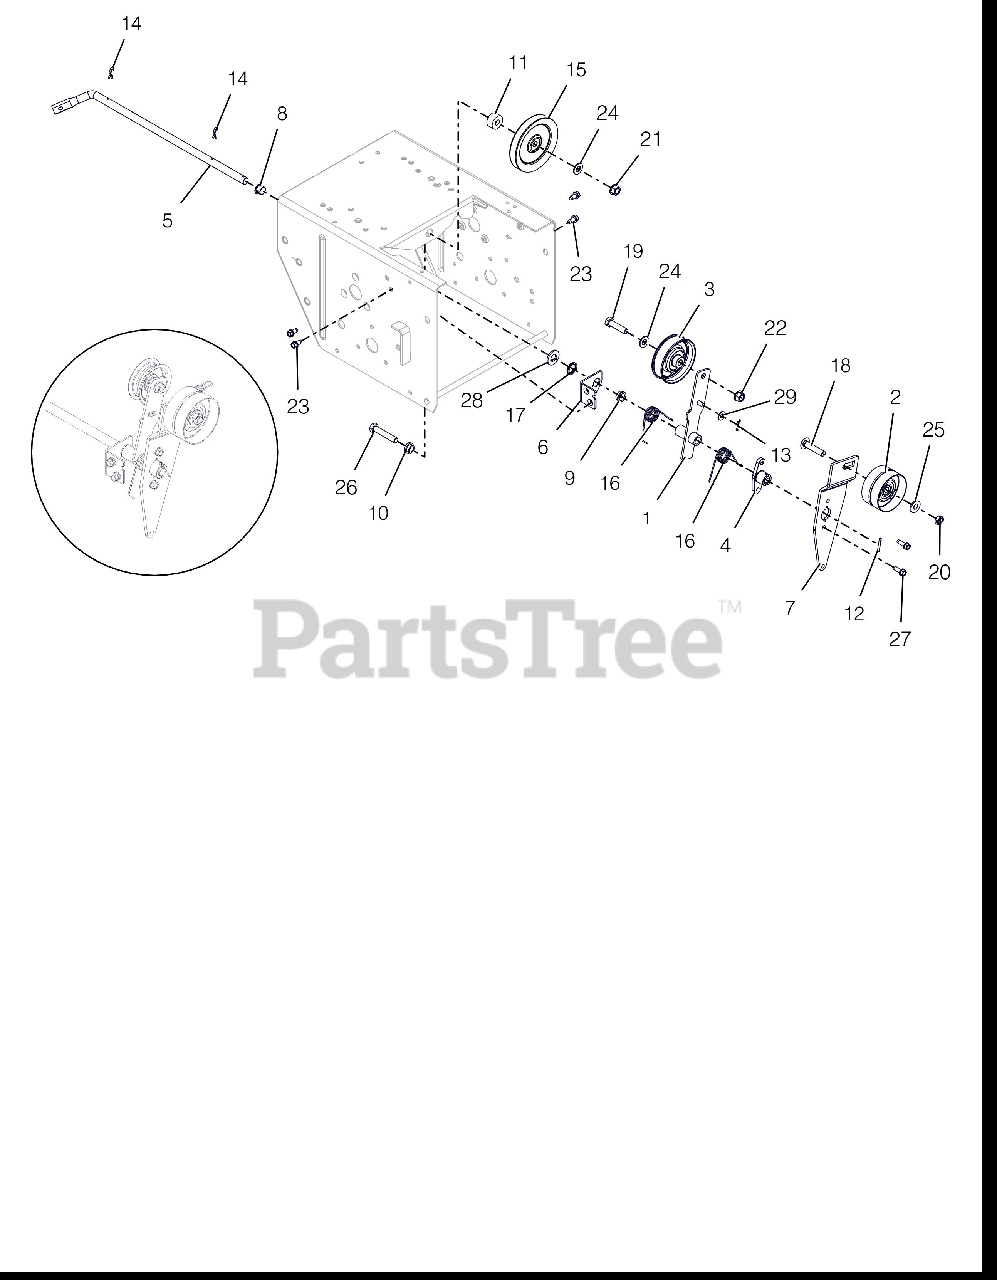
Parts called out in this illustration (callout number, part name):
1	ARM, TRACTION CLUTCH
2	IDLER, FLAT-2.75 OD X .375 ID
3	IDLER, FLAT - 3.05" X .75"
4	HUB, BRAKE ARM
5	ARM, ATTACHMENT
6	BRACKET, SUPPORT
7	ARM, IDLER-ATTACHMENT
8	BUSHING, POLYLINER-.50 SPLIT
9	BSHG,FLANGE .500X.625X.270X.75
10	BSHG, FLANGE .391X.56X.313X.75
11	BSHG,POCKET .391X.570X1.0X.450
12	PIN-ROLL .125X1.00
13	PIN-HAIR INT .06X.18X.77
14	CLIP, SPRING
15	SHV, .38"ID X 4.00"OD V-IDLER
16	SG-TORS .067X.88
17	WAVE SPRING .600X.875X.25FH
18	@BLT-RHDSSQNK .38-16X1.75 G5YZ
19	@BLT-HEX .38-16X1.50 GR5 YWZC
20	@NUT-LK-CTR-JAM .375-16 YWZC
21	@NUT-LK-TOP-FLG .38-16 YWZC
22	@NUT-LK-TOP-FLG .38-16 YWZC
23	SCR-TAP .25-20X.50 HWH TR YWZ
24	@WSHR-FL-STL.406X.812X.065 YWZ
25	@WSHR-FL-STL.38X.875X.083 YWZC
26	@BLT-HEX .38-16X2.00 GR5 YWZC
27	SCR-TAP-PM .25-20X.75 TR YWZ
28	@WSHR-FL-STL.531X1.06X.095YWZC
29	@WSHR-FL-STL.281X.62X.065 YWZC
